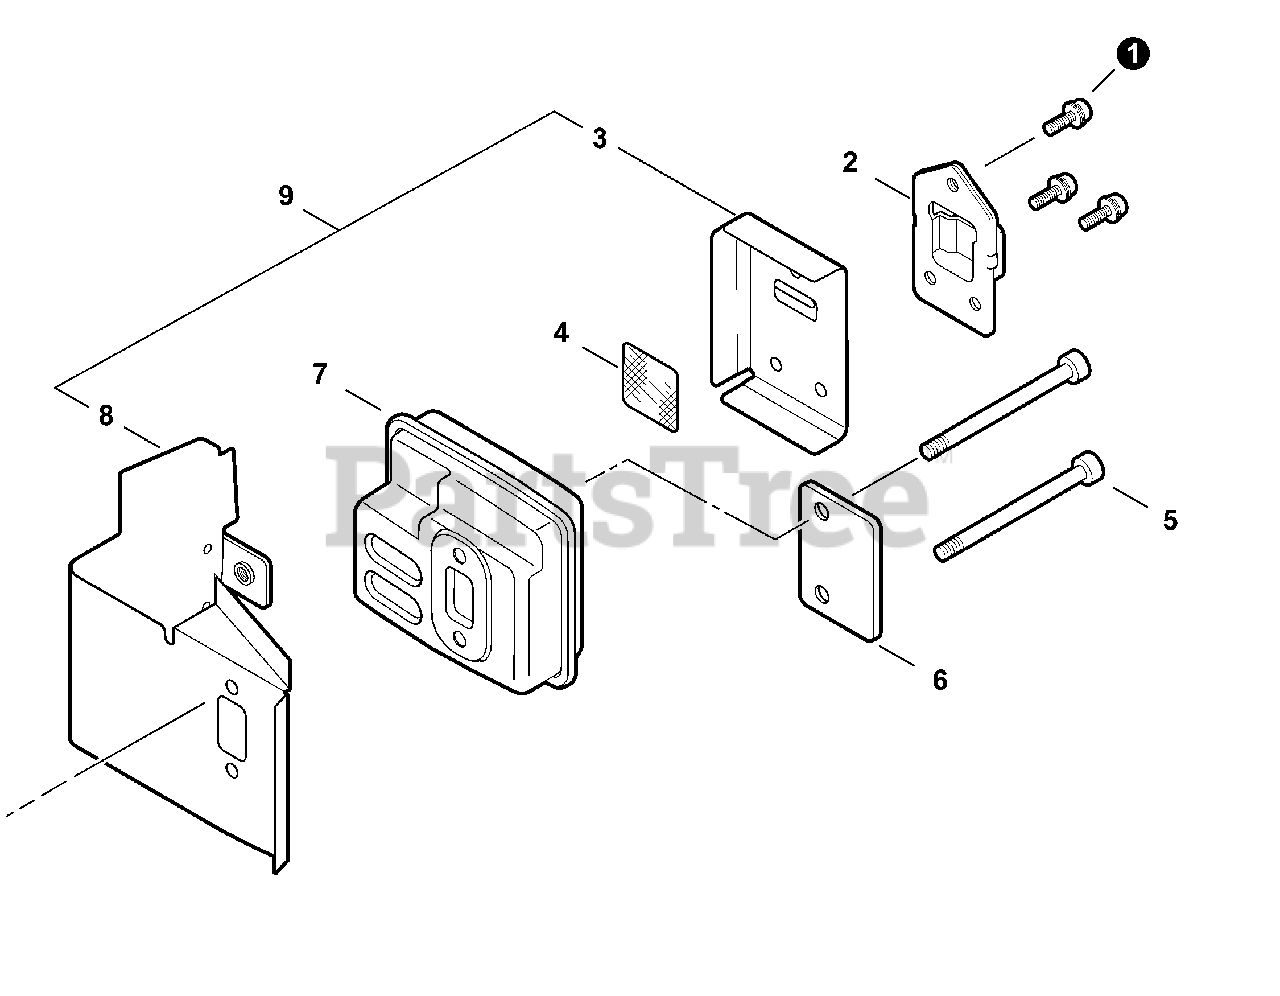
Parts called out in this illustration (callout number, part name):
1	SCREW 4×10
2	GUIDE, EXHAUST
3	GASKET, EXHAUST
4	SCREEN, SPARK ARRESTER
5	BOLT 5×55
6	PLATE, EYE
7	MUFFLER
8	HEAT SHIELD, EXHAUST
9	GASKET KIT
